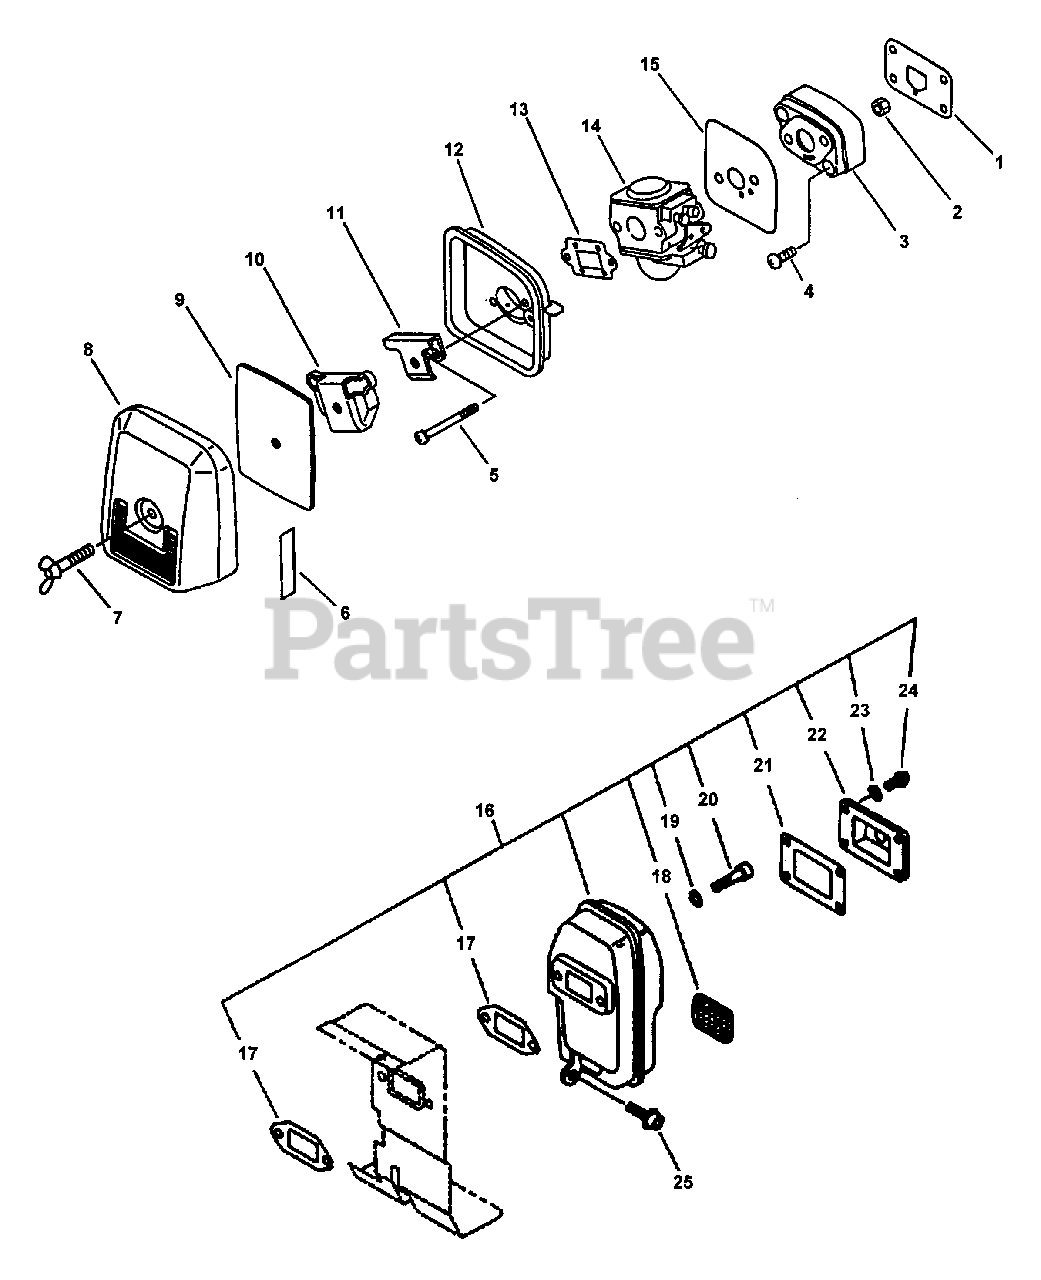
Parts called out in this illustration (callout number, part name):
1	GASKET, INTAKE
2	NUT M5
3	INSULATOR, INTAKE
4	SCREW 5×22
5	SCREW 5×55
6	LABEL, CHOKE
7	THUMBSCREW
8	COVER, AIR FILTER
9	FILTER, HEAVY-DUTY AIR
11	PLATE, PREVENT
12	AIR FILTER CASE ASSY
14	CARBURETOR - WT-417
15	GASKET, INTAKE
16	MUFFLER ASSY
17	GASKET, EXHAUST
18	SCREEN, SPARK ARRESTER
19	WASHER, FLAT 5.5×10×0.8
20	BOLT 5×60
21	GASKET, EXHAUST
22	GUIDE, EXHAUST
23	WASHER, SPRING 4 MM
24	SCREW - 4×12
25	BOLT 5×16
